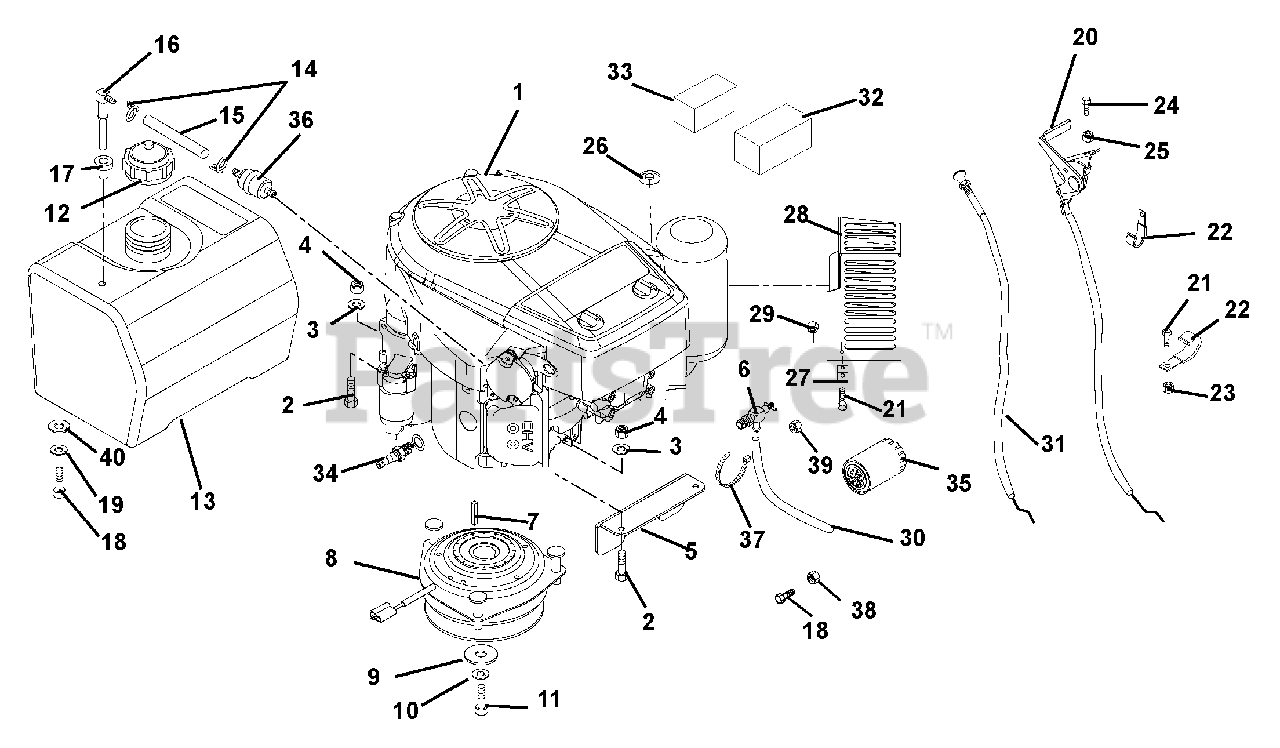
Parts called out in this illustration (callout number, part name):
1	ENGINE, 17 HP KAWASAKI FH500V
2	@BLT-HEX .31-18X1.75 GR5 YWZC
3	@WSHR-LK .31X.078 REG YWZC
4	@NUT-HEX .31-18 YWZC
5	BRACKET, CLUTCH
6	VALVE, OIL DRAIN
7	KEY-SQ .25 X 1.25 X .25 SAE
8	CLUTCH, ELECTRIC
9	WSHR-FL-STL .469X2.00X.25 YWZC
10	@WSHR-LK .44X.109 REG YWZC
11	BLT-HEX .44-20X3.00 GR5 YWZC
12	CAP - FUEL
13	TANK - FUEL
14	CLAMP-HOSE WIRE .490/.510X.116
15	GAS LINE-BULK 1/4" I.D.
16	FITTING, TANK
17	BSHG-FLG .375 X 1.062 X .625 R
18	@BLT-HEX .38-16X.75 GR5 YWZC
19	@WSHR-LK .38X.094 REG YWZC
20	CABLE - THROTTLE W/LINER
21	@BLT-HEX .31-18X.75 GR5 YWZC
22	J-CLAMP
23	@NUT-LK-NYL .312-18 YWZC
24	@SCR-MCH 10-24X.75 HWH YWZC
25	@NUT-LK-NYL 10-24 W/INSRT YWZC
26	WSHR-FL-STL .328X.87X.179 YWZC
27	BRACKET, MUFFLER GUARD
28	GUARD, MUFFLER
29	@NUT-LK-CTR .31-18 YWZC
30	TUBE, OIL DRAIN 8" CLEAR VINYL
31	CONTROL,CHOKE
32	AIR FLTR,PAPER KAWASAKI
33	AIR FLTR,FOAM KAW
34	PLUG, SPARK
35	FILTER,OIL - KAW
36	FUEL FILTER - KAWASAKI
37	CABLE TIE LG 5-1/2
38	@NUT-LK-CTR .38-16 YWZC
39	@NUT-LK-CTR .31-18 YWZC
40	@WSHR-FL-STL.406X.812X.065 YWZ
